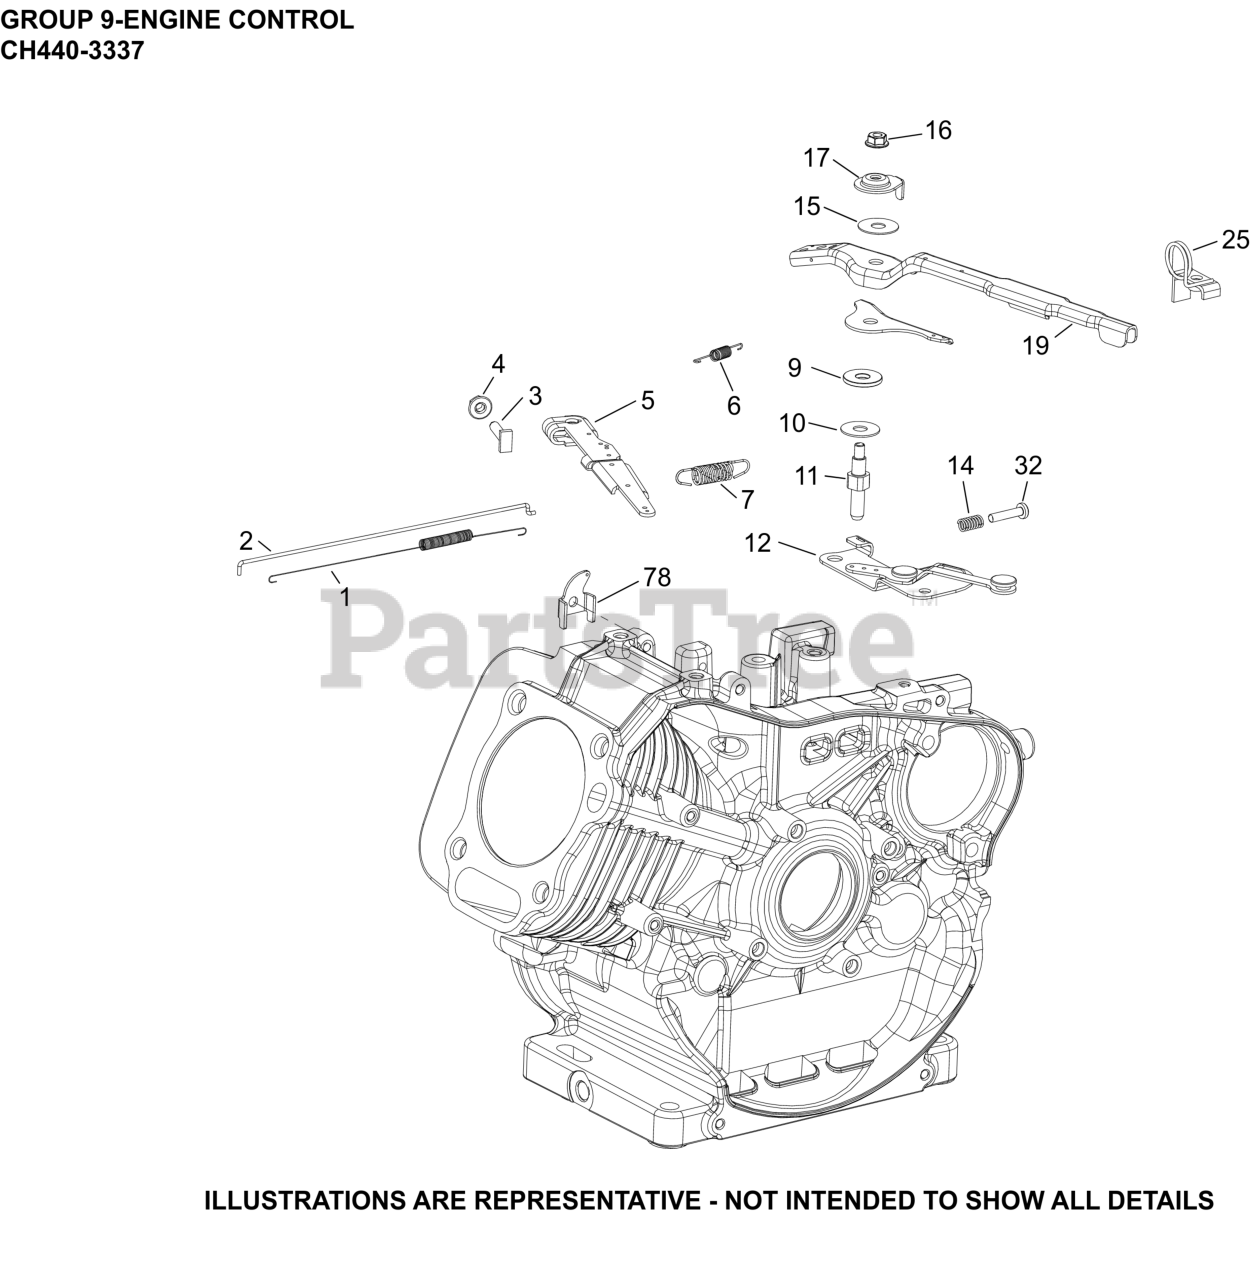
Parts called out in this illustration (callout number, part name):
1	SPRING, LINKAGE
2	LINKAGE, GOVERNOR
3	SCREW, RECTANGLE HEAD (M6)
4	NUT, HEX FLANGE (M6) - USE 14 100 16-S
5	KIT, GOVERNOR LEVER
6	SPRING, THROTTLE RETURN
7	SPRING, GOVERNOR
9	WASHER, NYLON CONTROL LEVER
10	WASHER, FLAT
11	STUD, CONTROL LEVER
12	BRACKET, CONTROLS ASSY
14	SPRING, COMPRESSION
15	WASHER, SPRING
16	NUT, HEX FLANGE LOCK (M6)
17	WASHER, CONTROL LEVER
19	CONTROL LEVER ASSEMBLY
25	BRACKET, ACCESSORY MOUNTING
32	SCREW, SPEED ADJUSTING
78	BRACKET, REMOTE CONTROL
